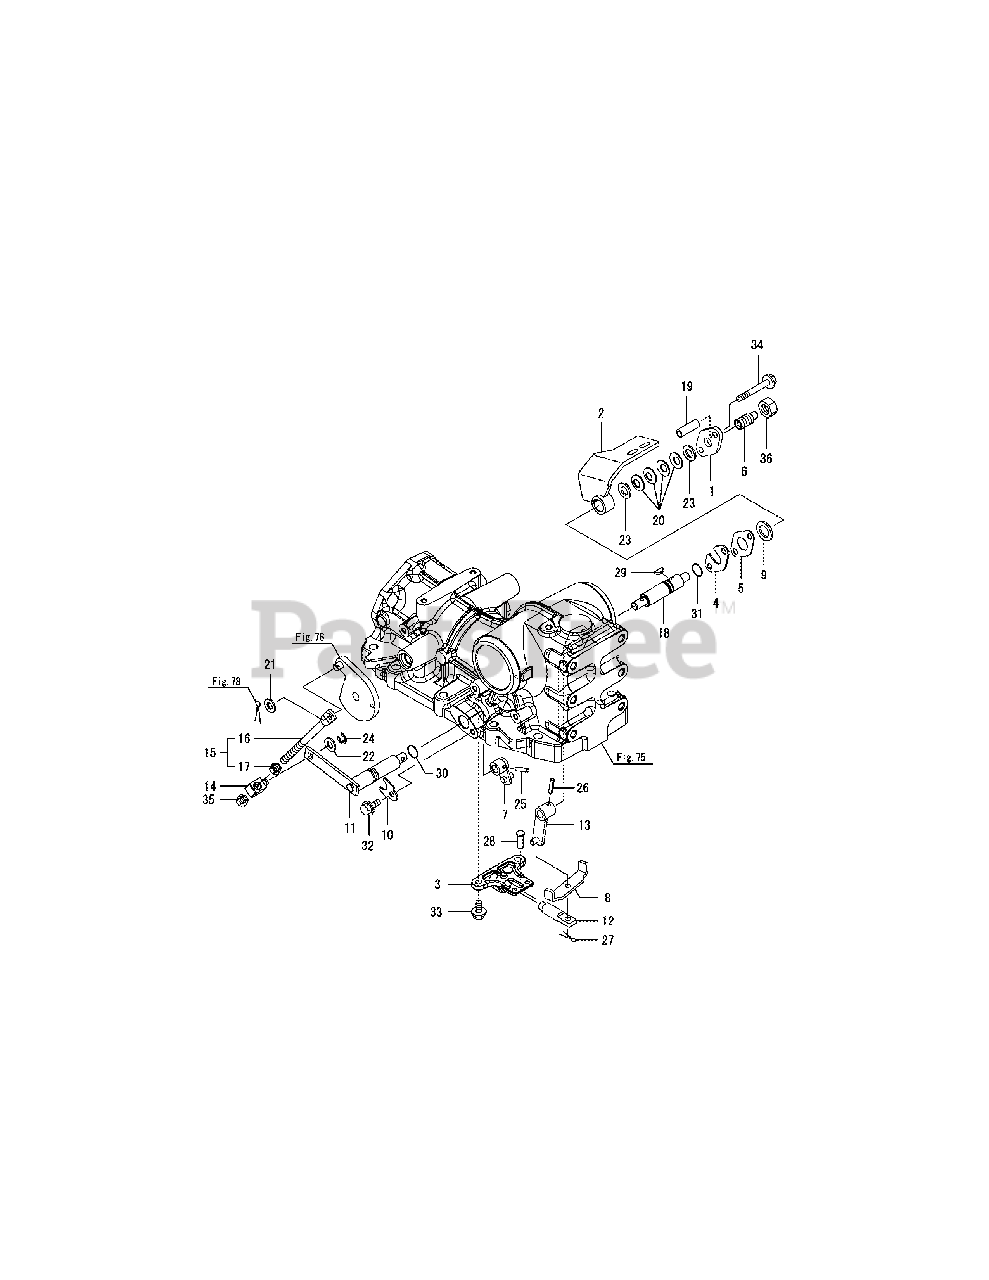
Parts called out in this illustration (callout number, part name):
6	BOLT, FRICTION
7	ARM,P CONTROL F.BACK
8	BAR, P CONTROL
9	PLATE, FRICTION
13	ARM, P CONTROL
16	ROD, FEED BACK
18	SHAFT, P LEVER
19	COLLAR, P LEVER
21	WASHER 10, POLISHED
22	WASHER 10, POLISHED
23	WASHER 12, POLISHED
25	SPRING PIN 5X25
26	SPRING PIN 5X25
27	COTTER PIN 2.0X20
29	KEY, WOODRUFF 3X13
30	O-RING 1A P-15.0
31	O-RING 1A P-15.0
32	BOLT M 8X 16 PLATED
33	BOLT M 8X 16 PLATED
34	BOLT M 8X 60 PLATED
